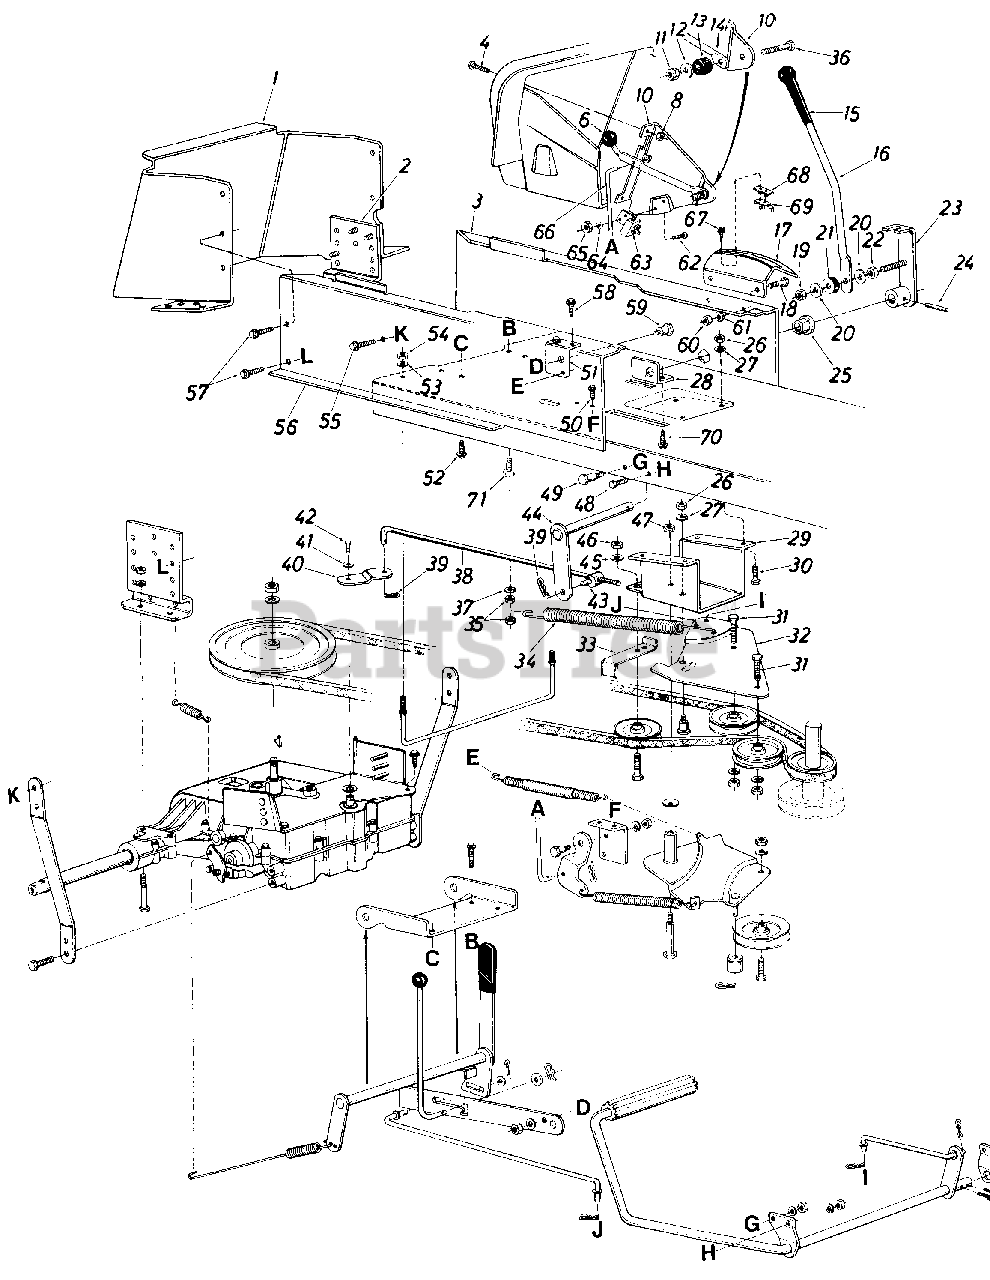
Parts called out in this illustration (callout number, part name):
1	Hitch Plate
2	Transaxle Support Bracket
3	Side Panel Upper Frame L.H.
4	Truss. Mach. Scr. 1/4-20 x .50" Lg.*
6	Ball Knob
8	Hex Sems Nut 1/4-20 Thd.*
10	Deck Clutch Control Brkt.
11	Hex Cent. L-Nut 1/4-20 Thd.
12	Fl-Wash. .281" I.D. x .734 O.D. x .063 Thk.
13	Rubber Wash. .330" I.D. x .87" O.D. x .32 Thk.
14	Blade Clutch Lever
16	Shift Lever
17	Shift Bracket
18	Hex Bolt 5/16-18 x .62" Lg.*
19	Hex Cent. L-Nut 5/16-18 Thd.
20	Fl-Wash. .344" I.D. x .875" O.D. x .063 Thk.
21	Rubber Wash. .330" I.D. x .87" O.D. x .32 Thk.
22	Hex Nut 5/16-18 Thd.*
23	Handle Mount Brkt. Ass'y.
24	Spring Pin Spiral 1/4" Dia. x 1.5" Lg.
25	Plastic Hex Bearing .625" I .D.
26	Hex Nut 5/16-18 Thd.
27	L-Wash. 5/16" I.D.*
28	Speed Control Shaft Brkt.
29	Transaxle Clutch Support Brkt.
30	Hex Bolt 5/16-18 x 2.50" Lg.*
31	Hex Bolt 3/8-16 x 1.25" Lg.
32	Idler Bracket Ass'y.
35	Hex Cent. L-Nut 1/4-20 Thd.
36	Hex Bolt 1/4-20 x 1.25" Lg.
37	L-Wash. 1/4" I.D.
38	Shift Link
39	Hairpin Cotter 3/8"
40	Shifter Bracket
41	Belleville Wash. .25" I.D. x .375" O.D.
42	Hex Bolt 1/4-28 x .62" Lg.
43	Pivot Bushing
44	Speed Control Shaft Ass'y.
45	Fl-Wash. .885" I.D. x .87 O.D. x .060 Thk.
46	Hex Cent. L-Nut 8/8-24 Thd.
47	Hex Cent. L-Nut 8/8-16 Thd.
48	Hex Bolt 8/8-16 x .62" Lg.*
49	Shoulder Bolt .500" Dia. x .340" Lg. (3/8-16)
50	Hex Thd. Rolling Scr. 1/4-20 x .50" Lg.
51	Parking Brake Cam Mtg. Brkt.
52	Hex Thd. Rolling Scr. 1/4-20 x .50" Lg.
53	L-Wash. 1/4" I.D.*
54	Hex Nut 1/4-20 Thd.*
55	Hex Wash. Hd. TT-Tap Scr. 3/8-16 x .5" Lg.
56	Side Panel Upper Frame-R.H.
57	Hex Thd. Rolling Scr. 5/16-24 x .50" Lg.
58	Hex Thd. Rolling Scr. 1/4-20 x .50" Lg.
59	Shoulder Bolt .435" Dia. x .160 (5/16-18)
60	Hex Nut 5/16-18 Thd.*
61	L-Wash. 5/16" I.D.*
62	Truss Mach. Scr. #10-24 x .50" Lg.*
63	Safety Switch
64	Ext. L-Wash. #10 I.D.*
65	Hex Nut #10-24 Thd.*
66	Deck Control Rod
67	Hex Wash. Hd. Scr. #8 x .50" Lg.
68	Insulator Nut Plate
69	Spring Switch
70	Hex Wash. Hd. AB-Tap Scr. 5/16 x .75" Lg.
71	Hex Wash. Hd. TT-Tap Scr. 1/4 x 1.5" Lg.
